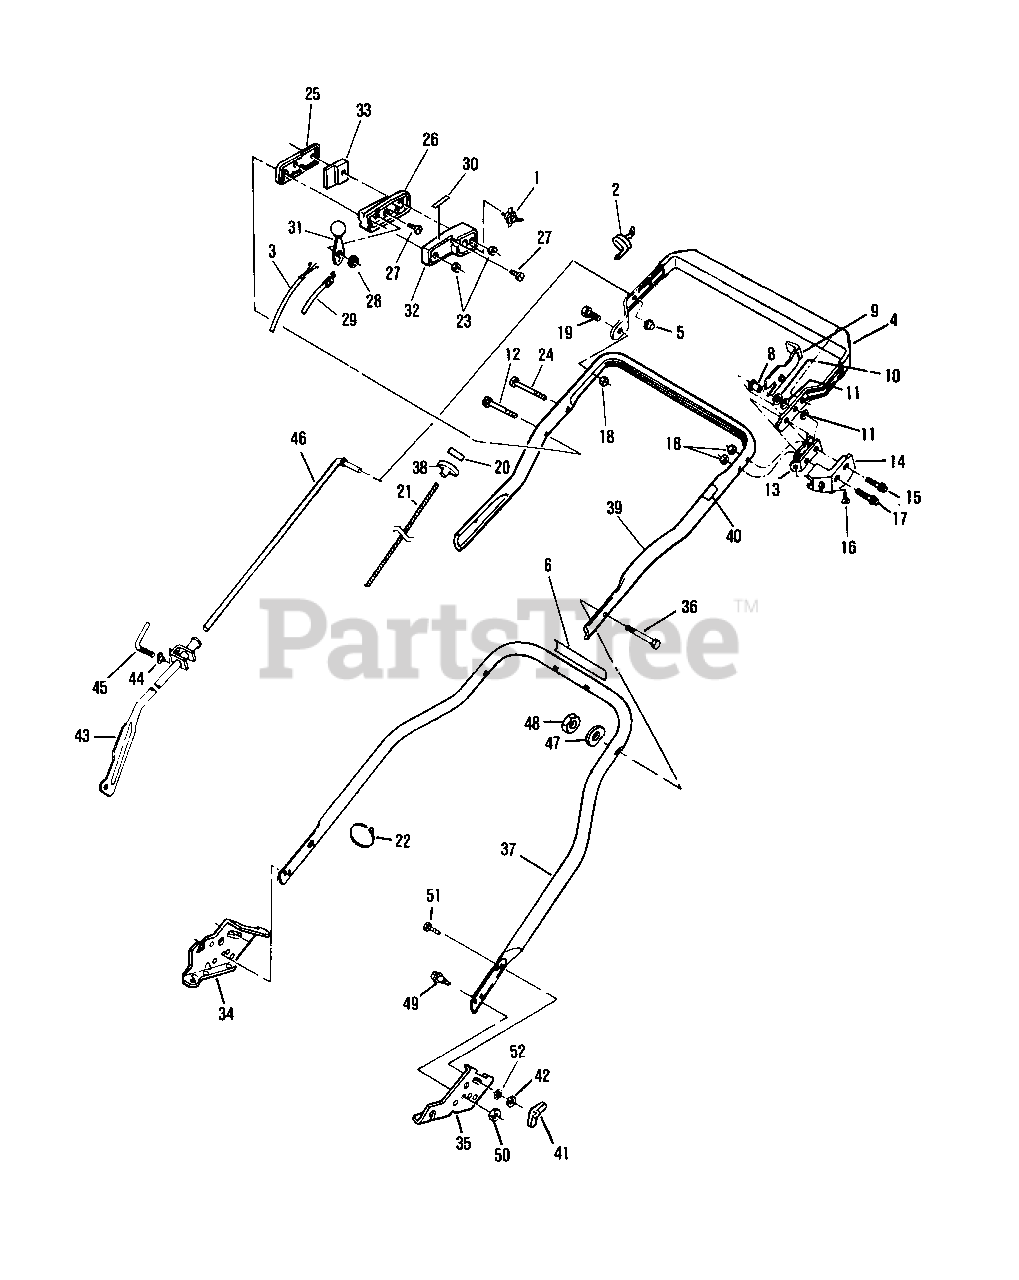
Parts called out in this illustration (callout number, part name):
1	Switch-ON-OFF
2	Rope Guide
3	Wiring Harness
4	Top Handle and Grip Assembly
5	Pushnut
6	Decal
8	Spacer-Flanged
9	Lever-Lockout
10	Washer-Plain
11	Washer-Spring
12	Screw
13	Down-Stop
14	Guard-Lockout
15	Bolt-Shoulder
16	Screw
17	Bolt-Shoulder-L.H.
18	Locknut
19	Bolt-Shoulder-R.H.
20	Clip-Rope Insert
21	Rope
22	Tie Strap
23	Nut-Hex Centerlock
24	Screw
25	Control Case-Outer
26	Case-Throttle Control
27	Screw
28	Washer-Spring
29	Cable Throttle
30	Decal-Throttle Control
31	Lever/Knob
32	Case-Throttle-Inner
33	Escutcheon Plate
34	Bracket-Handle-R.H.
35	Bracket-Handle-L.H.
36	Screw
37	Handle Section-Bottom
38	Handle
39	Handle Section-Center
40	Decal-Drive Lockout
41	Wing Nut
42	Washer
43	Control Lever Assembly
44	Nut-Control Lever Clamp
45	Lever-Rod Clamp
46	Rod-Control
47	Washer
48	Nut
49	Bolt
50	Nut
51	Screw
52	Lockwasher
